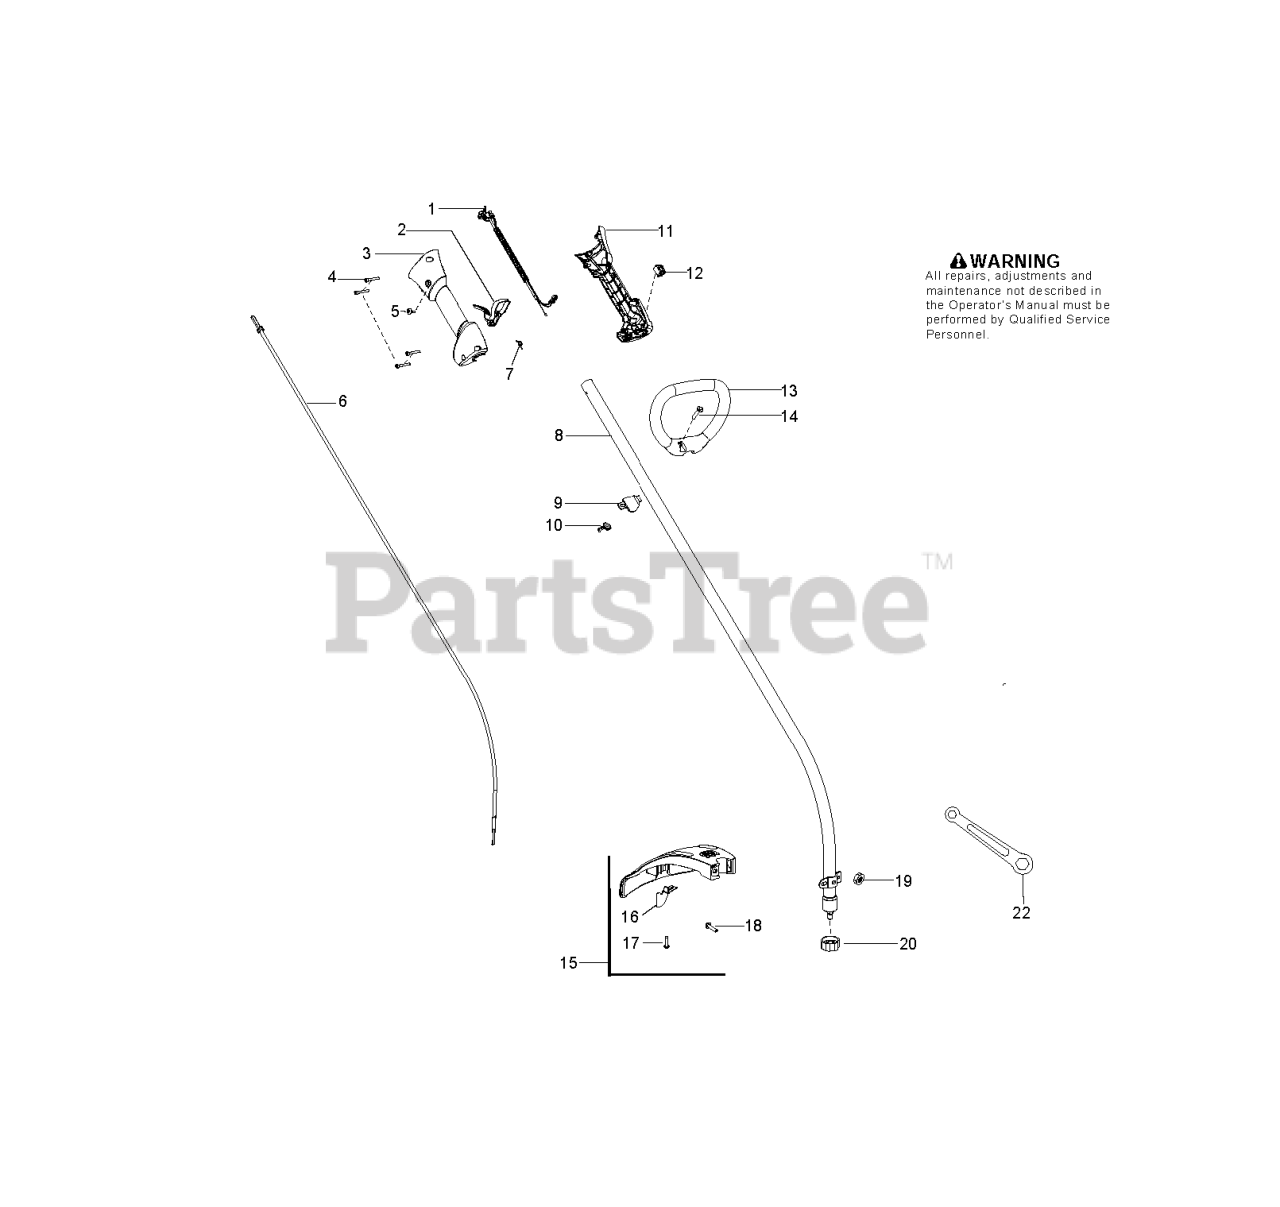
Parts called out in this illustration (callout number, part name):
6	FLEX SHAFT 52"
7	SPRING TRIGGER
8	KIT DRIVE SHAFT
9	CLAMP ASSIST HANDLE
10	WINGNUT, TYPE 2
14	BOLT, TYPE 2
15	SHIELD ASSY
16	KIT - LIMITER - LINE
18	BOLT, TYPE 2
